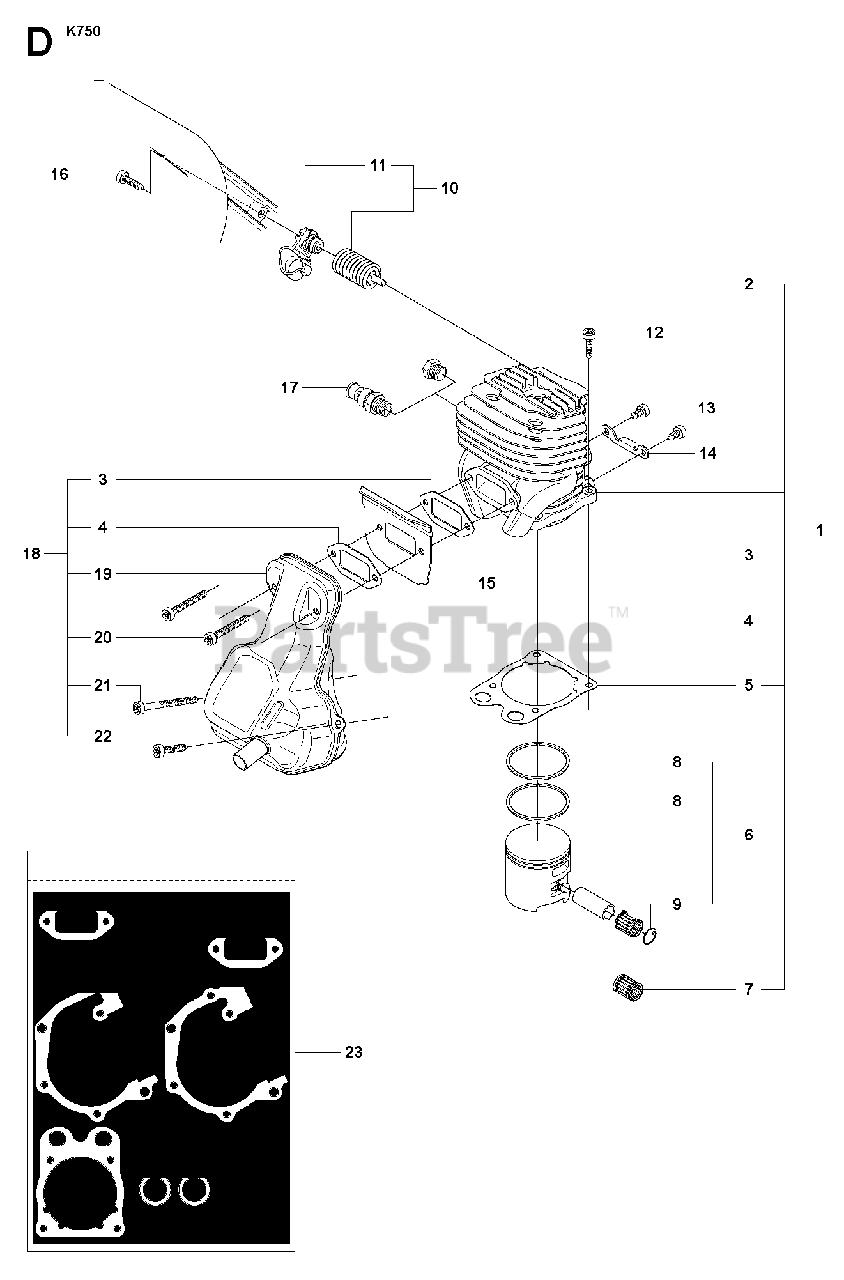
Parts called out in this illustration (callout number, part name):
1	CYLINDER ASSYIncl. 2 - 7
4	GASKET
6	PISTON ASSYIncl. 8, 9
7	NEEDLE BEARING
8	PISTON RING
10	ANTIVIBRATION ELEMENTIncl. 11
12	SCREW ITXSCM
13	SCREW ITXSCM
15	COOLING AIR CONDUCTOR
16	SCREW ITXSCT
17	DECOMPRESSION VALVE
18	MUFFLER KITIncl. 3, 4, 19 - 22
19	MUFFLER ASSY
20	SCREW ITXSCM
21	SCREW ITXSCM
22	SCREW ITXSCM
23	GASKET KITIncl. 3 - 5, 24 - 27
27	SEALING RING
